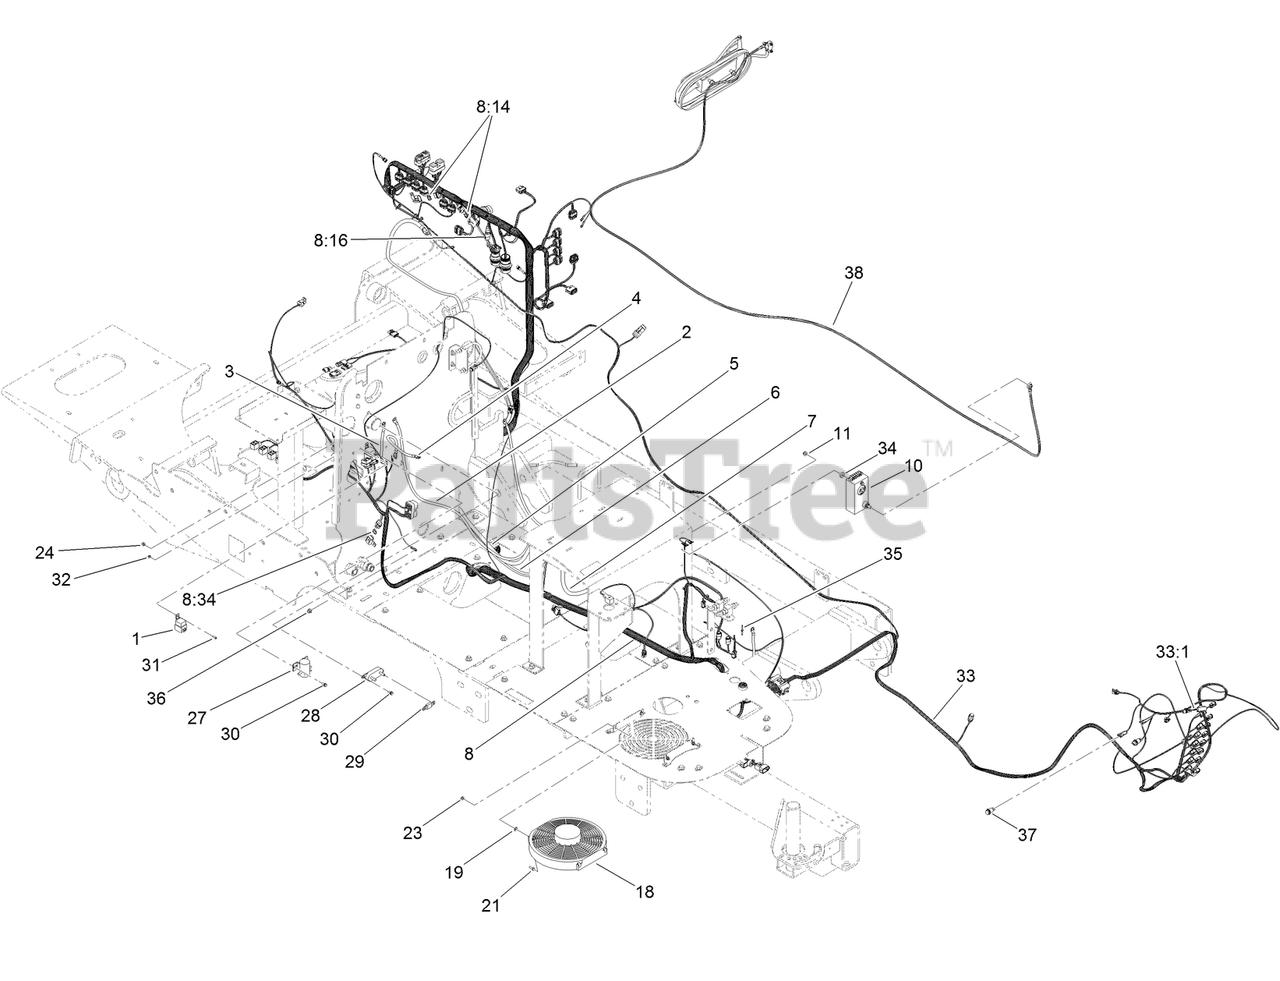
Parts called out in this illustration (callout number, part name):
1	RELAY-MINI
2	CABLE-BATTERY, POSITIVE
3	CABLE-BATTERY, POSITIVE
4	CABLE-BATTERY, POSITIVE
5	CABLE-BATTERY, POSITIVE
6	CABLE-BATTERY, NEGATIVE
7	CABLE-BATTERY, NEGATIVE
8	HARNESS-WIRE, MAIN
8:14	FUSE-BLADE, 10 AMP
8:16	RESISTOR-120 OHM
8:34	FUSE-BLADE, 30 AMP
11	NUT-HF, NI
18	FAN-ELECTRIC
19	WASHER-FLAT
21	SCREW-HH
23	NUT-HF
24	NUT-FLANGE, NI
27	SOLENOID-RELAY 12V, 300A
28	HOLDER-FUSE
29	FUSE-100A
30	SCREW-HHF
31	SCREW-HSBH
32	NUT-HF
33	HARNESS-WIRE, THRUST FRAME
33:1	FUSE-BLADE, 5 AMP
35	RIVET-POP
36	NUT-LOCK, HHF
37	LAMP-INDICATOR, LED
38	GROUND STAKE KIT
